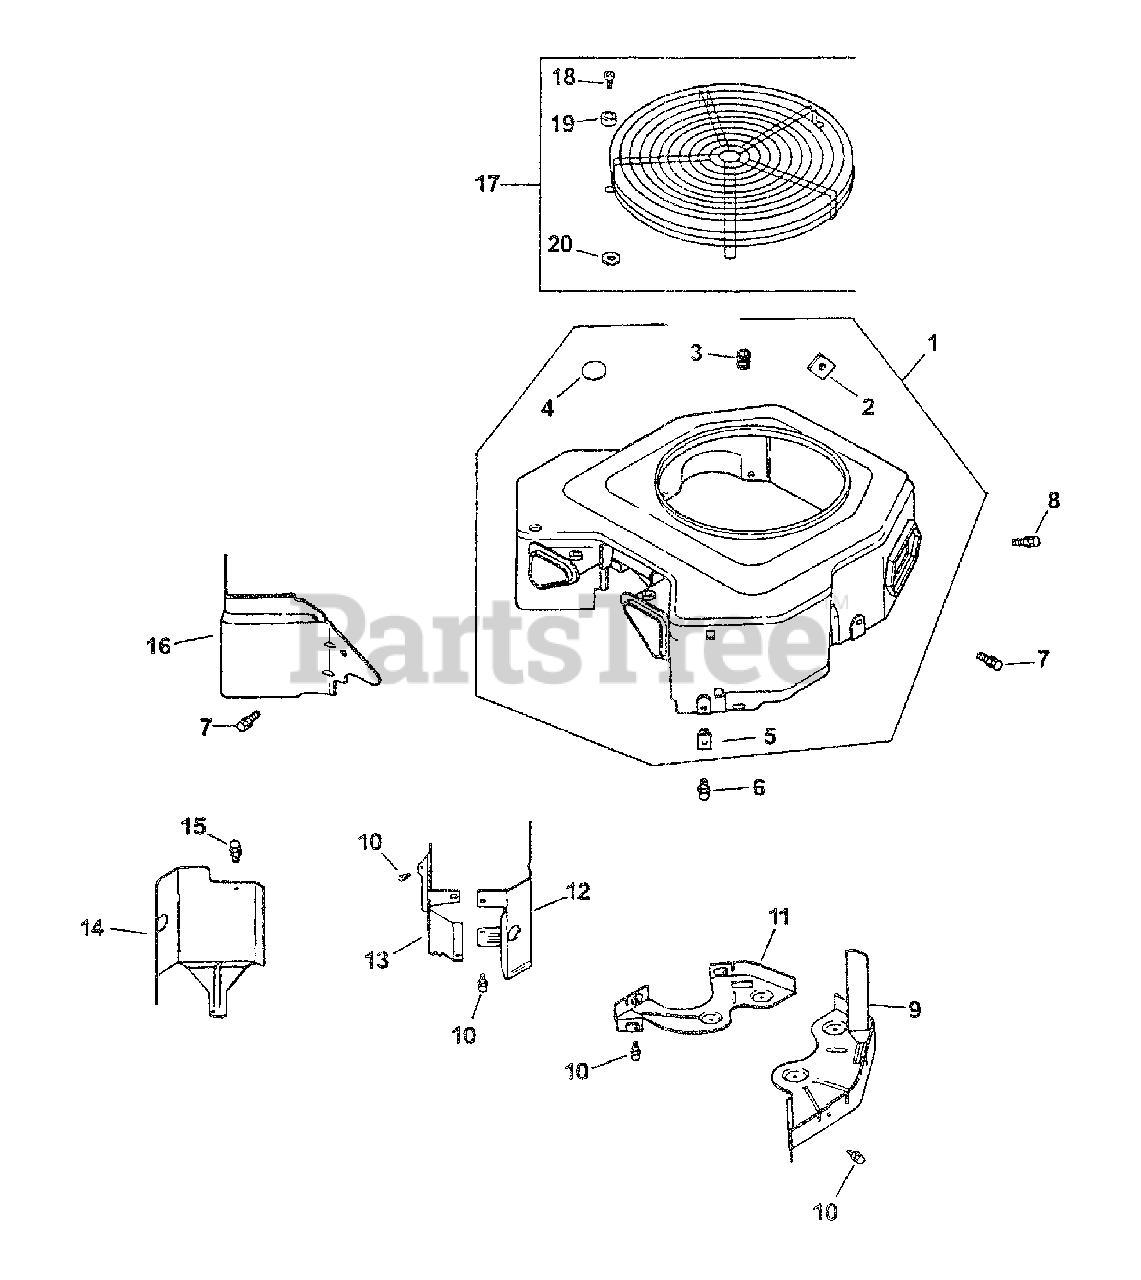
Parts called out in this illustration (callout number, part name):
1	Housing, Blower
2	Nut, Plastic
4	Plug, Button 9/16"
5	Nut, Plastic
6	Screw, Hex Flange
7	Screw, Hex Flange
8	Screw, Hex Flange
9	Plate, Backing - #2 Side
10	Screw, Hex Flange
11	Plate, Backing - #1 Side
12	Baffle, Cylinder Barrel - #2 Side
13	Baffle, Valley - #1 Side
14	Baffle, Cylinder Barrel - #1 Side
15	Screw, Hex Flange
16	Baffle, Valley - #2 Side
18	Screw, Pan Head
19	Spacer
20	Washer, Plain 1/4"
